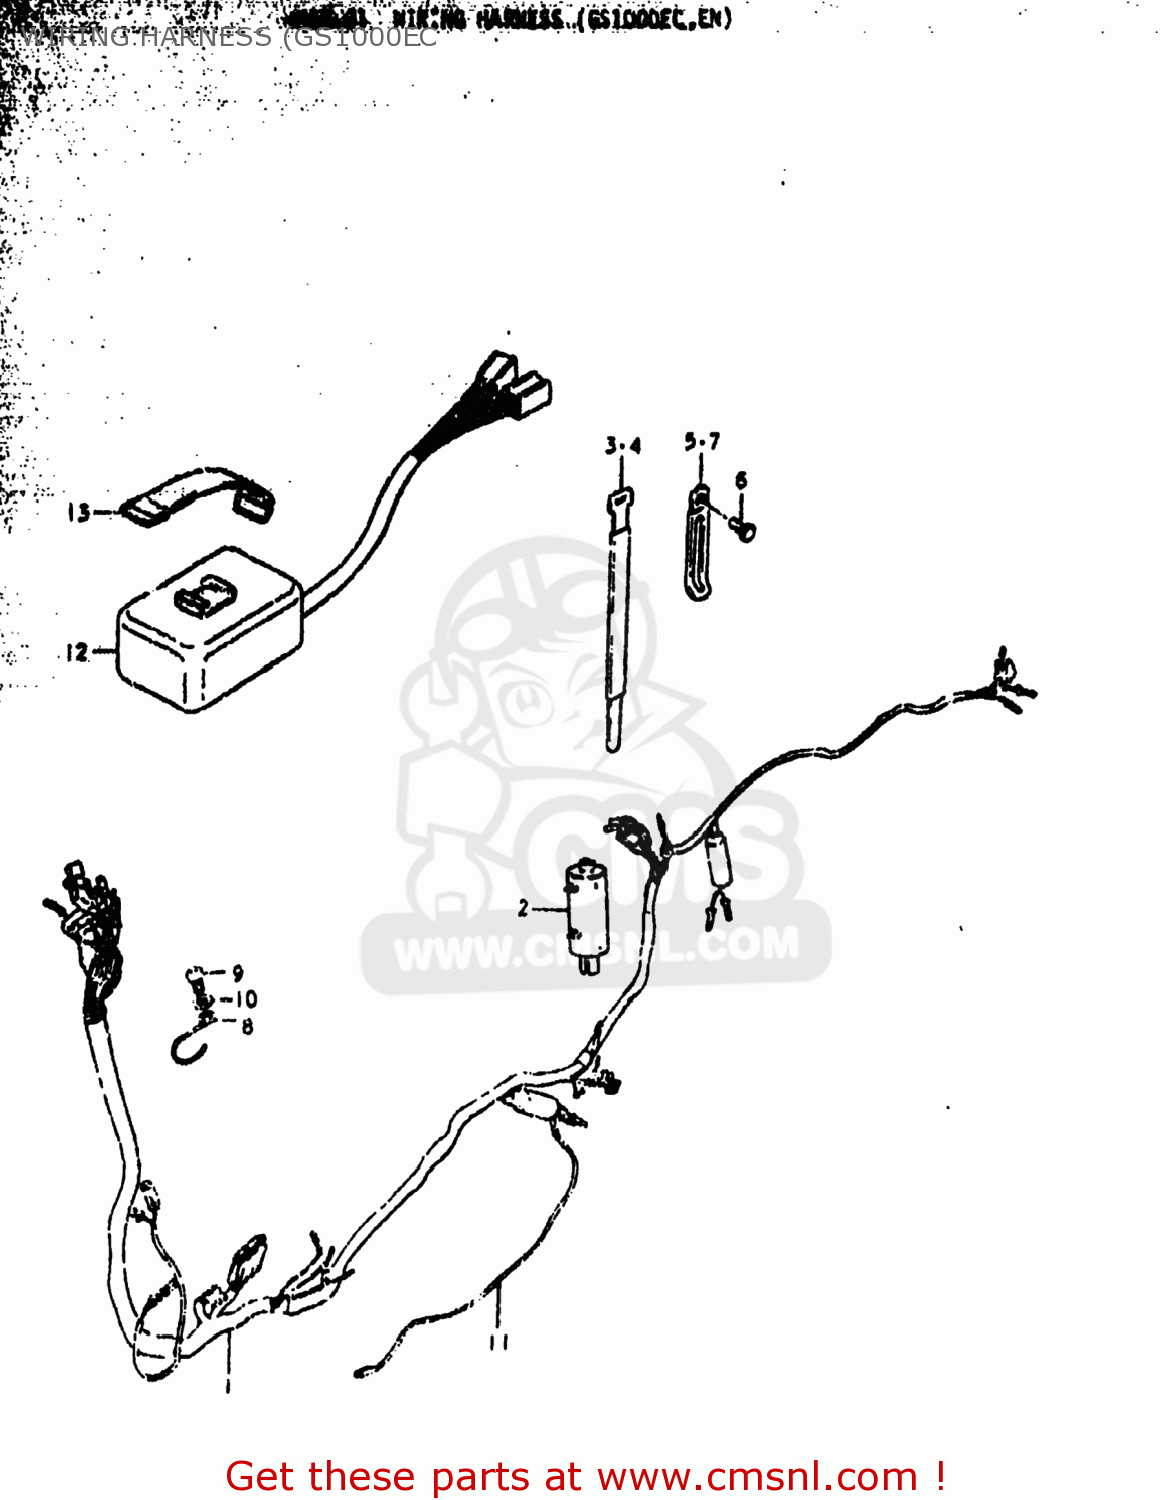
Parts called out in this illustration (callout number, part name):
1	HARNESS,WIRING
2	BOOT,WIRING HARNESS
3	CLAMP(L:120)
4	CLAMP
5	CLAMP
6	BOLT
7	CLAMP
8	GUIDE,WIRING HARNESS
9	SCREW 6X12
10	WASHER 6MM
11	WIRE
12	UNIT,TURN SIGNAL CONTROL
13	BAND
